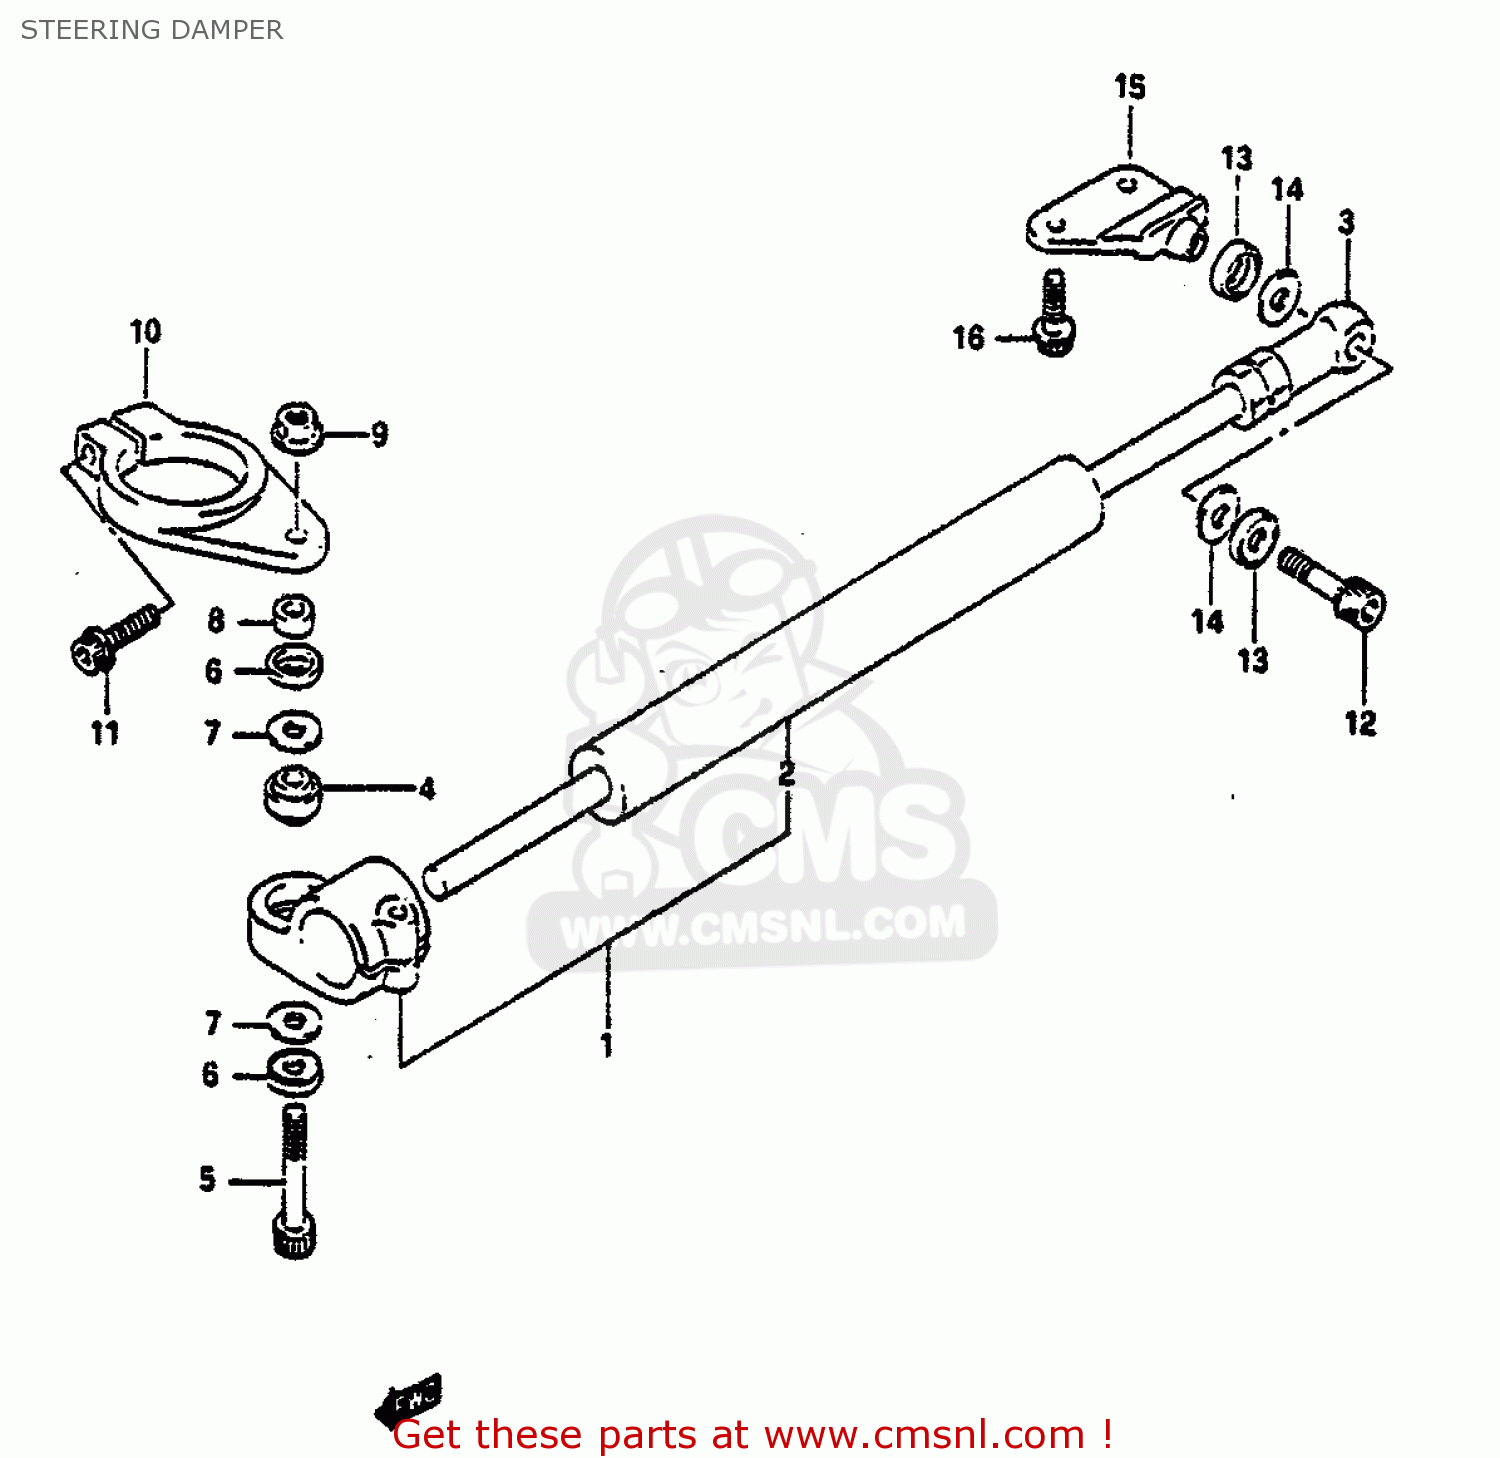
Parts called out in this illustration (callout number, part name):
1	DAMPER ASSEMBLY,STEERING
2	DAMPER,STEERING
3	PILLOW BALL,ROD END
4	BEARING(8X17.5X11)
5	BOLT
6	7
7	SHIM
8	SPACER (8.4X14X6)
9	NUT
10	BRACKET,STEERING DAMPER
11	BOLT
12	BOLT, FRONT RH
13	14
14	SHIM
15	BOSS,STEERING DAMPER
16	BOLT 6X20
